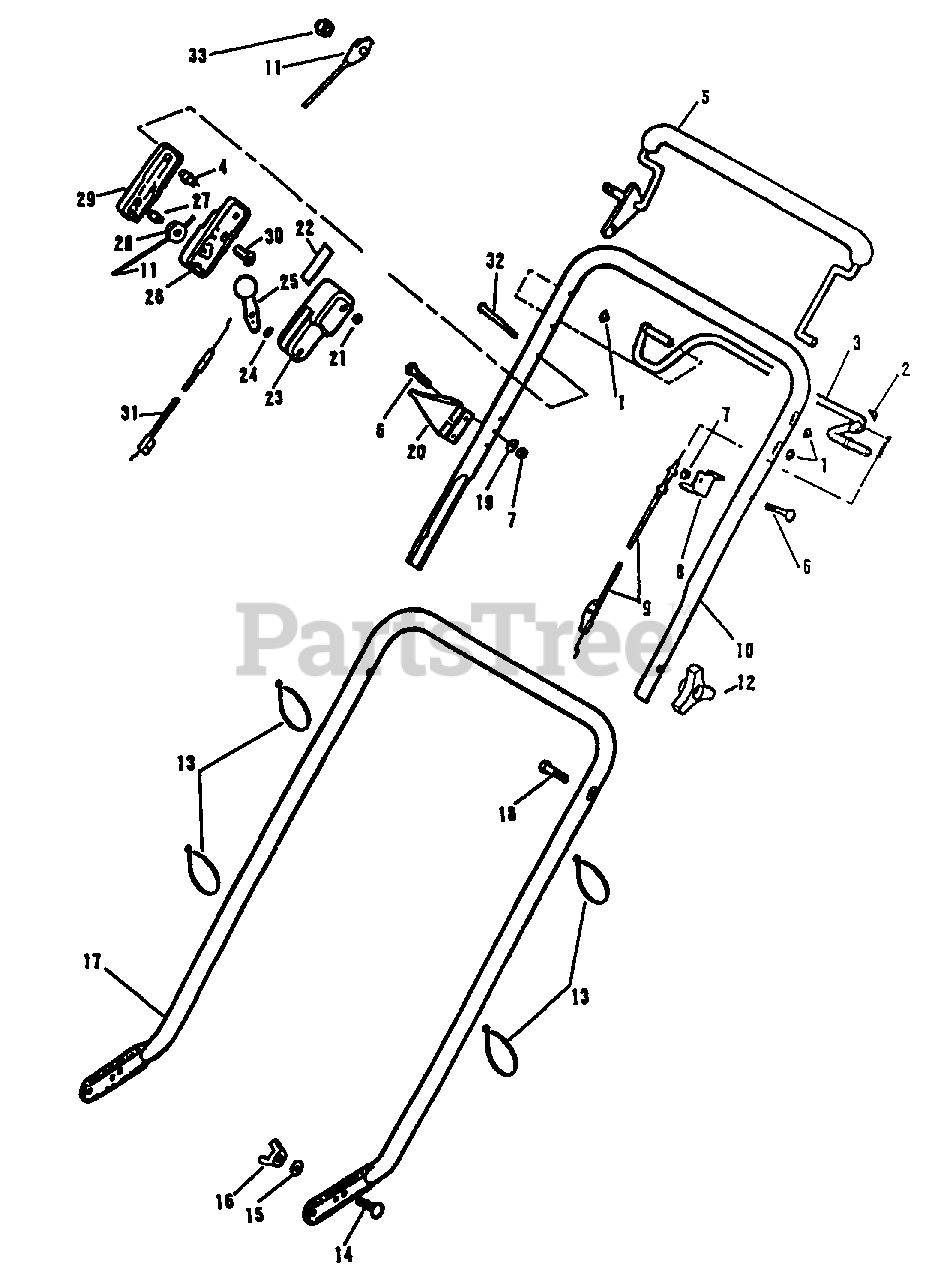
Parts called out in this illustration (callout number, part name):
1	Palnut
2	Palnut
3	Self Propel Bail
4	Column
5	Control Lever Assembly
6	Screw
7	Nut
8	Conduit Anchor
9	Control Cable Assembly
10	Handle Section-Top
11	Engine Control Cable
12	Handle Knob
13	Tie Strap
14	Bolt-Handle to Handle Bracket
15	Washer
16	Wing Nut
17	Handle Section-Lower
18	Screw
19	Washer
20	Rope Guide Assembly
21	Nut
22	Decal-Throttle Control
23	Throttle Case-Inner
24	Washer
25	Lever and Knob Assembly
26	Throttle Case-Center
27	Pin
28	Pulley
29	Control Case-Outer
30	Screw
31	Throttle Cable
32	Screw
33	Acorn Nut
